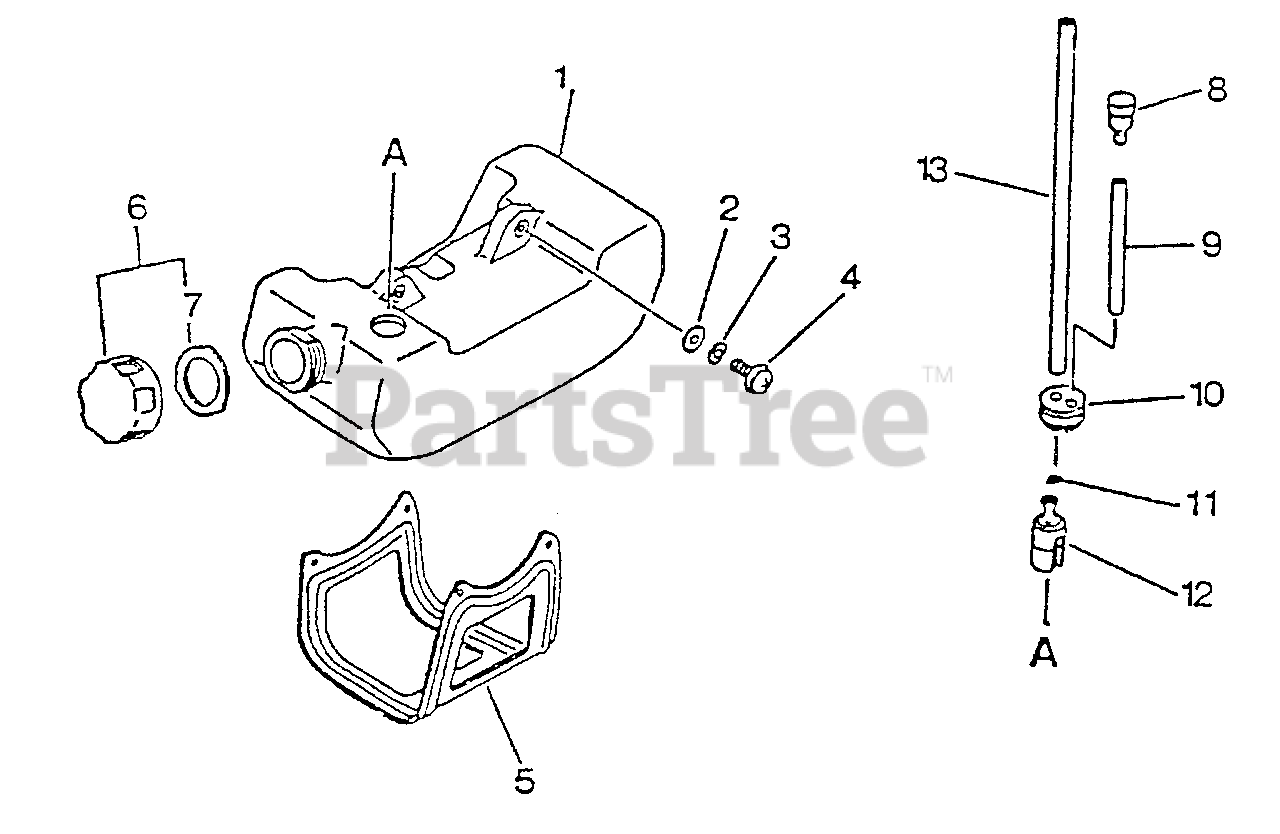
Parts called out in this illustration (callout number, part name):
1	TANK, FUEL
2	WASHER 5.5×12×0.8
3	WASHER, SPRING 5
4	SCREW 5×16
5	GUARD, FUEL TANK
6	CAP ASSY
7	GASKET, FUEL CAP
8	VENT ASSY
9	PIPE, FUEL 3x-5x-70 BLACK
10	GROMMET, FUEL
11	CLIP 6 MM
12	FILTER, FUEL
13	PIPE, FUEL 3x-5x-180
